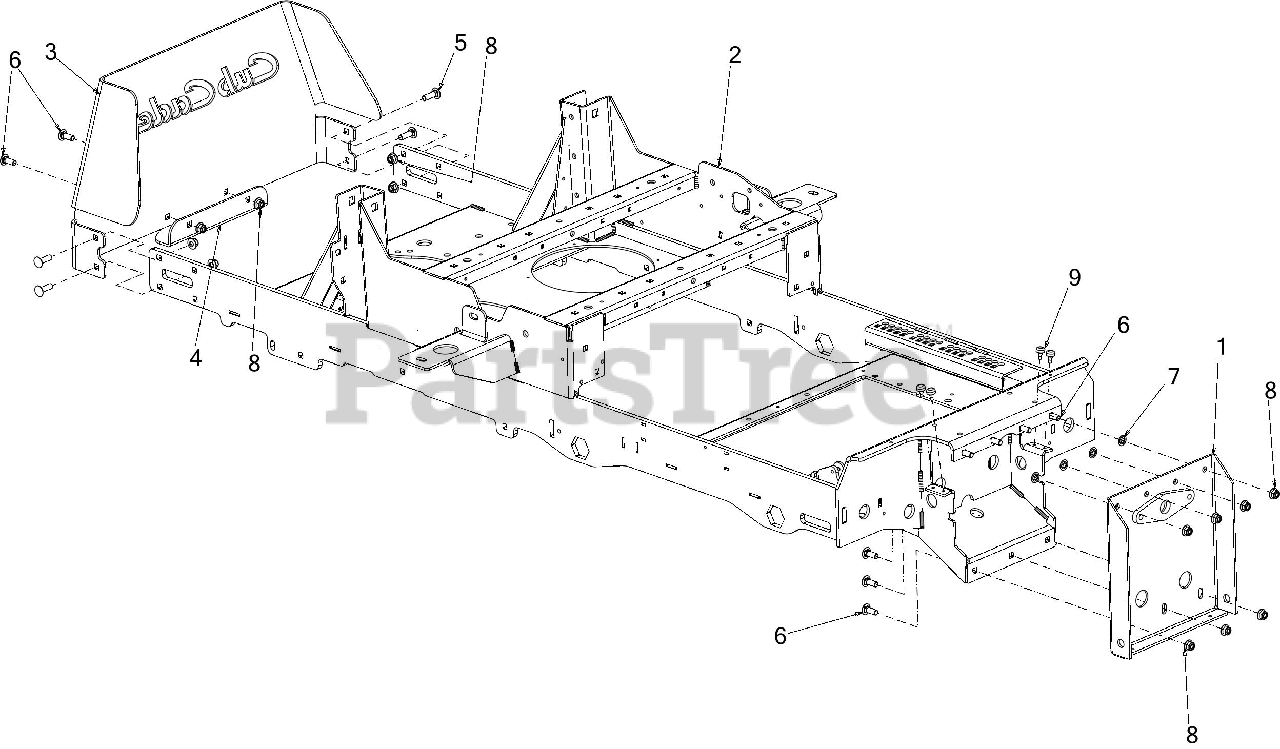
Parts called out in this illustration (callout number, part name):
2	FRAME ASSEMBLY
3	REAR TAILGATE BUMPER
4	HITCH TANK BRACKET
5	CARRIAGE BOLT 3/8-16 X1.25 GR5
6	CARRIAGE BOLT 3/8-16 x 1.00 GR5
9	BUMPER, .62 DIA x .3
